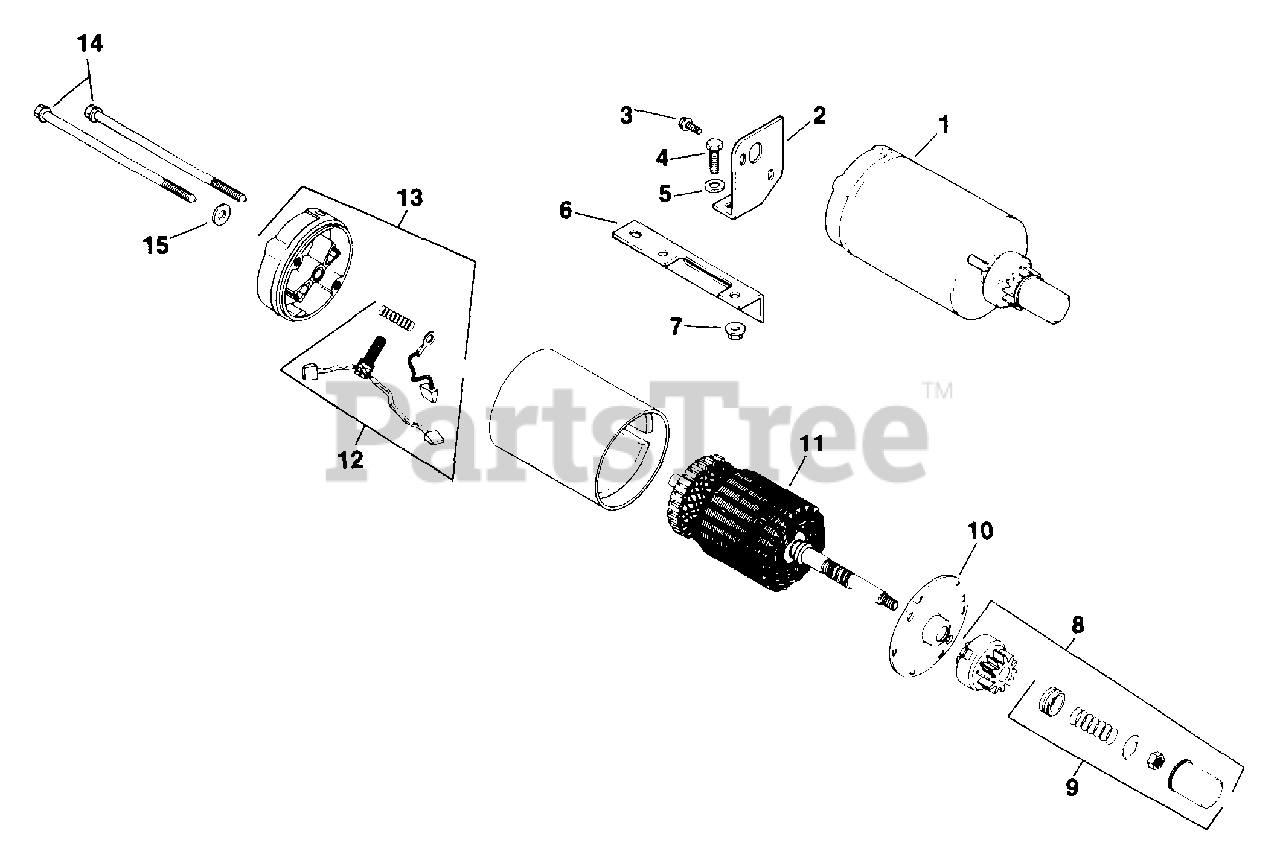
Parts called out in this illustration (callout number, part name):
1	STARTER - USE 41 098 06
3	SCREW, WSH HD TAP 1/4-20X3/4" USE 25 086 100-S
4	SCREW, CAP HD 1/4-20x5/8"
5	WASHER, FLAT 1/4" (O.D. 5/8")
7	PALNUT, 1/4-20
10	CAP - USE 41 081 05
11	ARMATURE - DISCONTINUED
12	KIT - USE 82 755 28
13	CAP - USE 52 227 03
14	BOLT, STARTER 1/4-20X5-1/16"
15	WASHER, FLAT 1/4" (O.D. 5/8")
